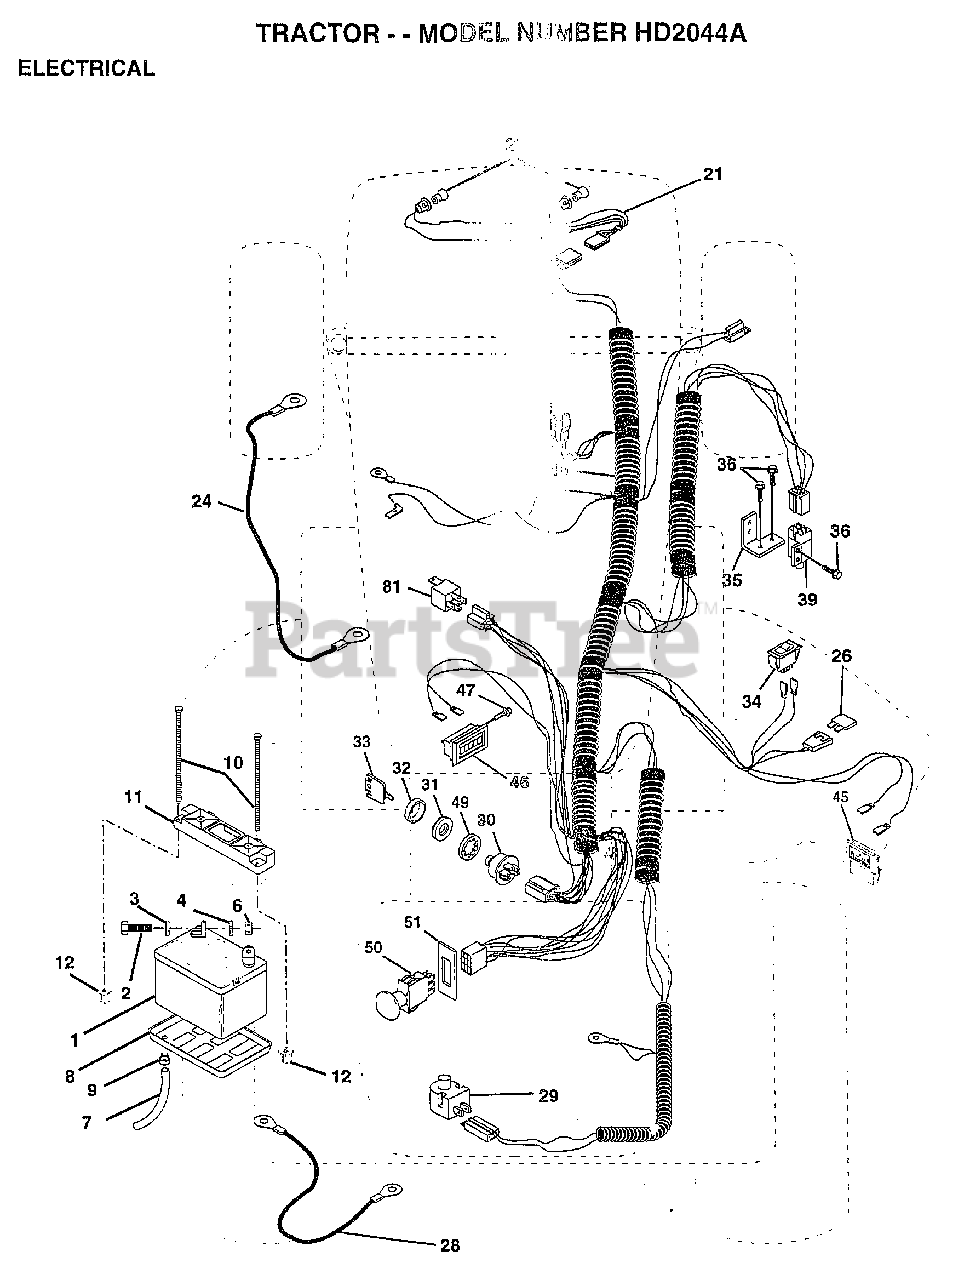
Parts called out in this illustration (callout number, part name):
3	WASHER
4	LOCKWASHER
7	"DRAIN TU T, BATT"
8	"TRAY T, BATTERY"
9	HOSE CLAMP T
21	"HARNESS,LIGHT SOC"
22	HEADLAMP BULB
24	CABLE.BATTERY.RED
26	FUSE HYT
28	CABLE.GRND.6GA.21
29	SWITCH SEAT
30	SWITCH T
31	NUT IGNITION
33	KEY
34	SWITCH LT
36	SCREW
38	BRACKET SWITCH IN
39	SWITCH INTERLOCKT
40	HARNESS.IGN.ONAN
45	AMMETER
46	HOUR METER T
47	SCREW
51	RING RETAIN PTO
81	RELAY ASSY T
